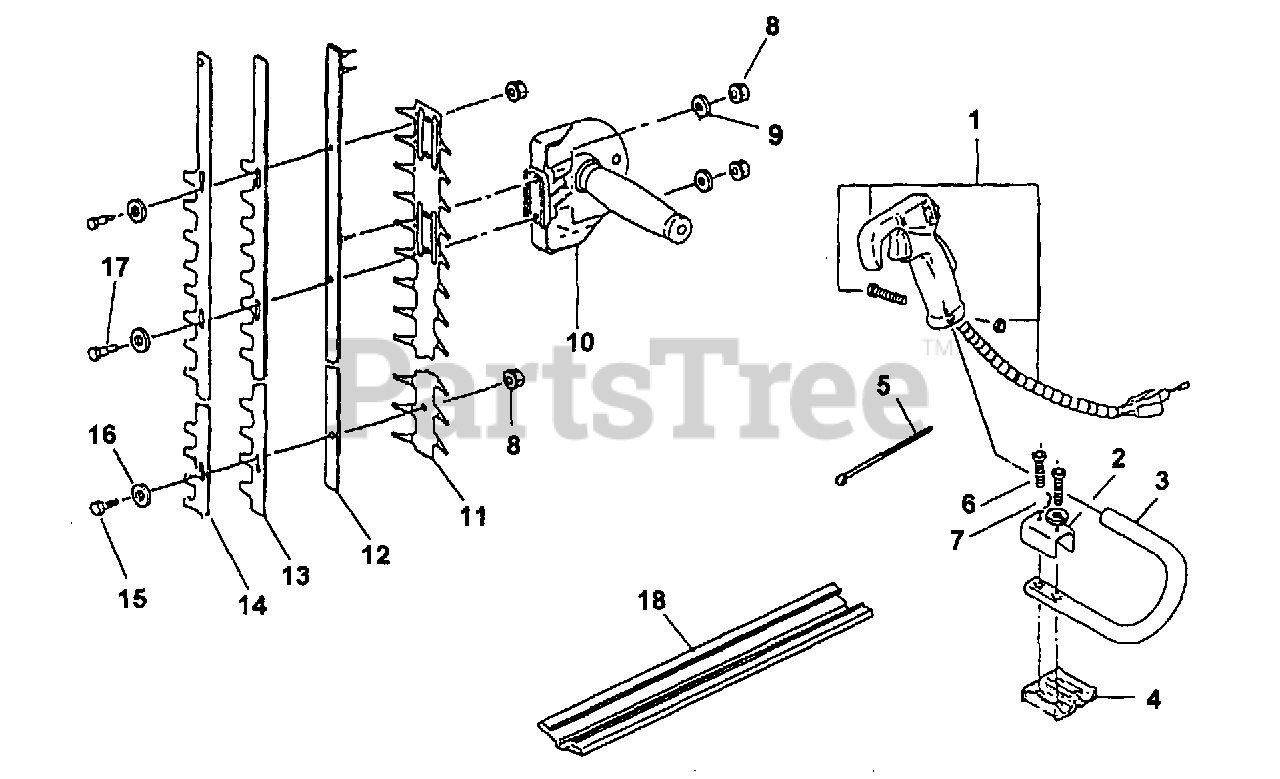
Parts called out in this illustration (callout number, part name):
1	THROTTLE LEVER ASSY.
4	ABSORBER
5	WIRE BAND
6	SOCKET SCREW (M5 X 45)
7	LOCK WASHER (M5)
8	HEX NUT (M6)
9	WASHER (M6)
10	HANDLE ASSY
11	PROTECTOR
12	CUTTER GUIDE
13	CUTTER BLADE (B)
14	CUTTER BLADE (A)
15	STEP BOLT (SHORT)
16	CUTTER WASHER
17	STEP BOLT (LARGE)
